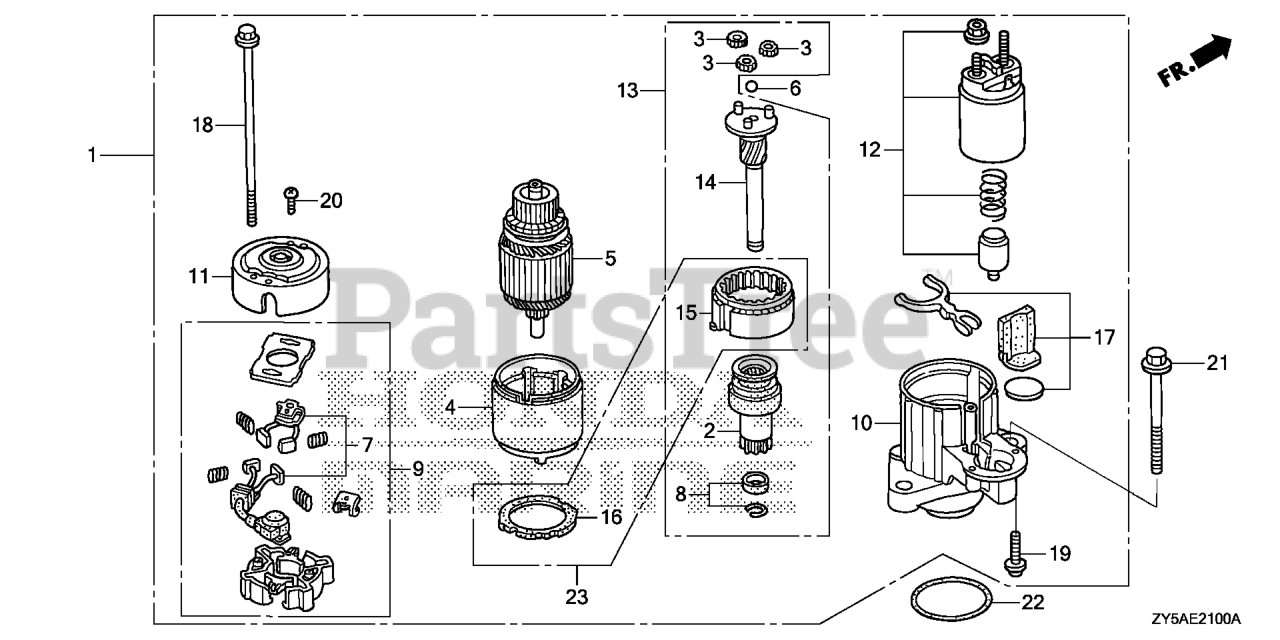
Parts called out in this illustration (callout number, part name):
1	STARTER MOTOR ASSY.
2	CLUTCH, OVERRUNNING
3	GEAR ASSY., PLANETARY
6	BALL, STEEL
8	STOPPER SET, SLEEVE
9	HOLDER, BRUSH
10	BRACKET, FR.
11	BRACKET, RR.
12	SWITCH ASSY., MAGNET
13	SHAFT ASSY., CLUTCH
14	SHAFT ASSY., GEAR
18	BOLT A, THROUGH
19	SCREW, PAN (6X22)
20	SCREW, PAN (5X8)
21	BOLT, FLANGE (10X90)
22	O-RING (59.4X3.1)
23	GEAR ASSY. (INNER)
